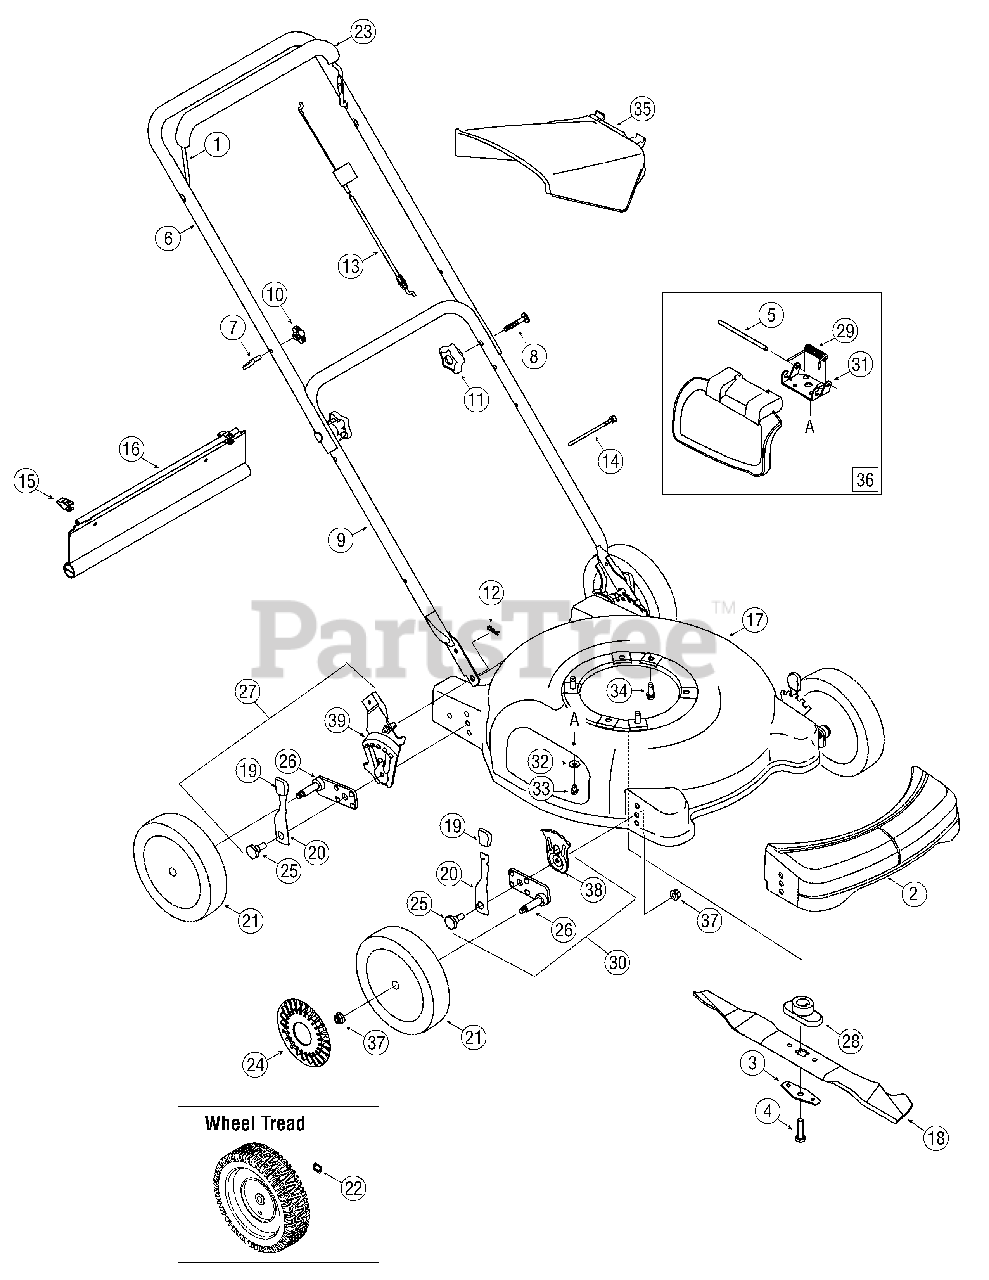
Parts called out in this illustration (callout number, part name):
2	Front Cover
3	Blade Bell Support
5	Hinge Pin
8	Carriage Bolt
11	Star Knob
12	Hairpin Clip
13	Control Cable, 39"
14	Cable Tie
15	Hinge Clip
19	Height Adjustment Knob
20	Spring Lever
21	Wheel Assembly, 8 x 2.125
22	Wave Washer
23	Snap-On Bail Cover
24	Hubcap
25	Shoulder Bolt
26	Pivot Arm Assembly - RH Front
26	Pivot Arm Assembly - RH Rear
27	Handle Bracket Assembly RH
28	Blade Adapter
29	Torsion Spring
30	Height Adjust. Assembly RH
33	Hex Washer Hd. TT Screw
34	TT Sems Screw
35	Chute Deflector
36	Mulching Plug Assembly
38	Height Adjustment Plate
